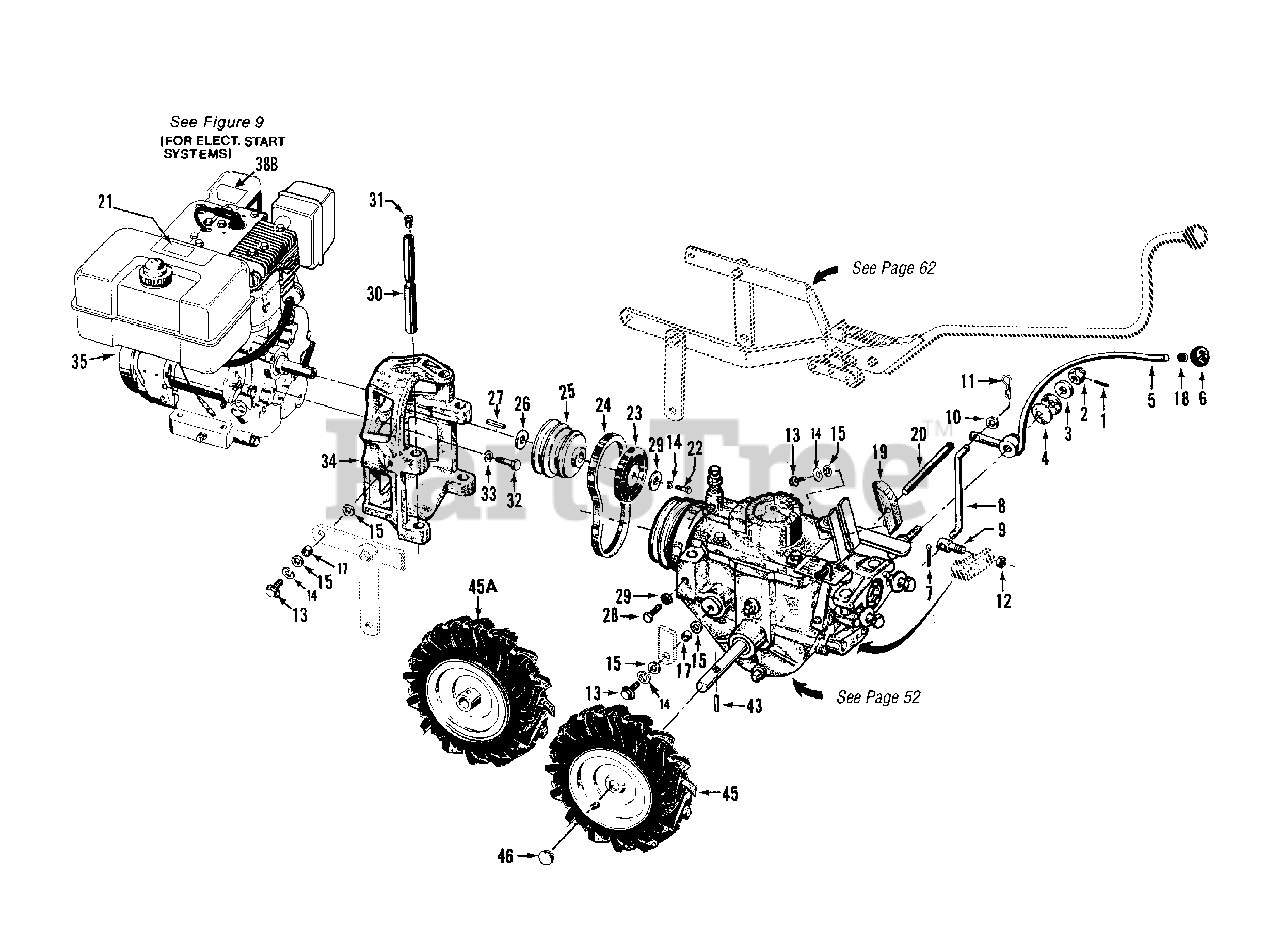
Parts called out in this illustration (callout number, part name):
1	Pin-spring, 1/8"
2	Nut-castle (slotted), 1/2"-20
3	Washer-shoulder, 1/2"
4	Washer-disc spring
5	Lever-wheel speed shift
6	Knob-wheel speed shift lever
7	Pin-cotter, 3/32" x 1"
8	Rod-connecting rod, wheel speed shift lever
9	Swivel-connecting rod
10	Washer-flat, 5/16", S.A.E
11	Pin-hair cotter.
12	Locknut-hex hd., 5/16"-18
13	Bolt-flanged hex hd., 3/8-16 x 1"
14	Lockwasher-spring lock, 3/8"
15	Washer-flat, 3/8", S.A.E.
17	Bushing-spacer, 19/64" (.300"lg.)
18	Ring-retaining (tolerance ring)
19	Block-belt adjustment, 3-7/8"
20	Rod-belt adjust., 7" with measuring gauge
21	Decal-engine stabilization
22	Bolt-hex hd., 3/8-24 x 1-1/2"
23	Disc-reverse
24	Belt-forward drive (no substitute due to extra strength required)
25	Pulley-engine power take off
26	Shim-engine pulley, 1/16"
26	Shim-as above, 1/32"
27	Key-engine pulley, 3/16"sq. x 2-1/2"
28	Bolt-hex hd., 5/16-18 x 1", Grade 5
29	Nut, hex, 5/16-18
30	Bar-engine mounting
31	Plug-thread protector, red plastic
32	Bolt-hex hd., 5/16-24 x 1-1/8"
33	Lockwasher-spring lock, 5/16"
34	Mount-engine to tiller
35	Briggs & Stratton Engine-Recoil or electric start. (Electric start requires key switch starting system.)
38B	Decal-hot surface warning (E682L)
43	Pin-roll, 5/16" x 1-1/2"
45	Wheel & Tire Assy-bar tread, left side, 4:80 x 8" tubeless tire with valve stem, on one-piece steel wheel
45A	Wheel & Tire Assy-bar tread, right side. Same as above but for right side of tiller
46	Cap-wheel hub
